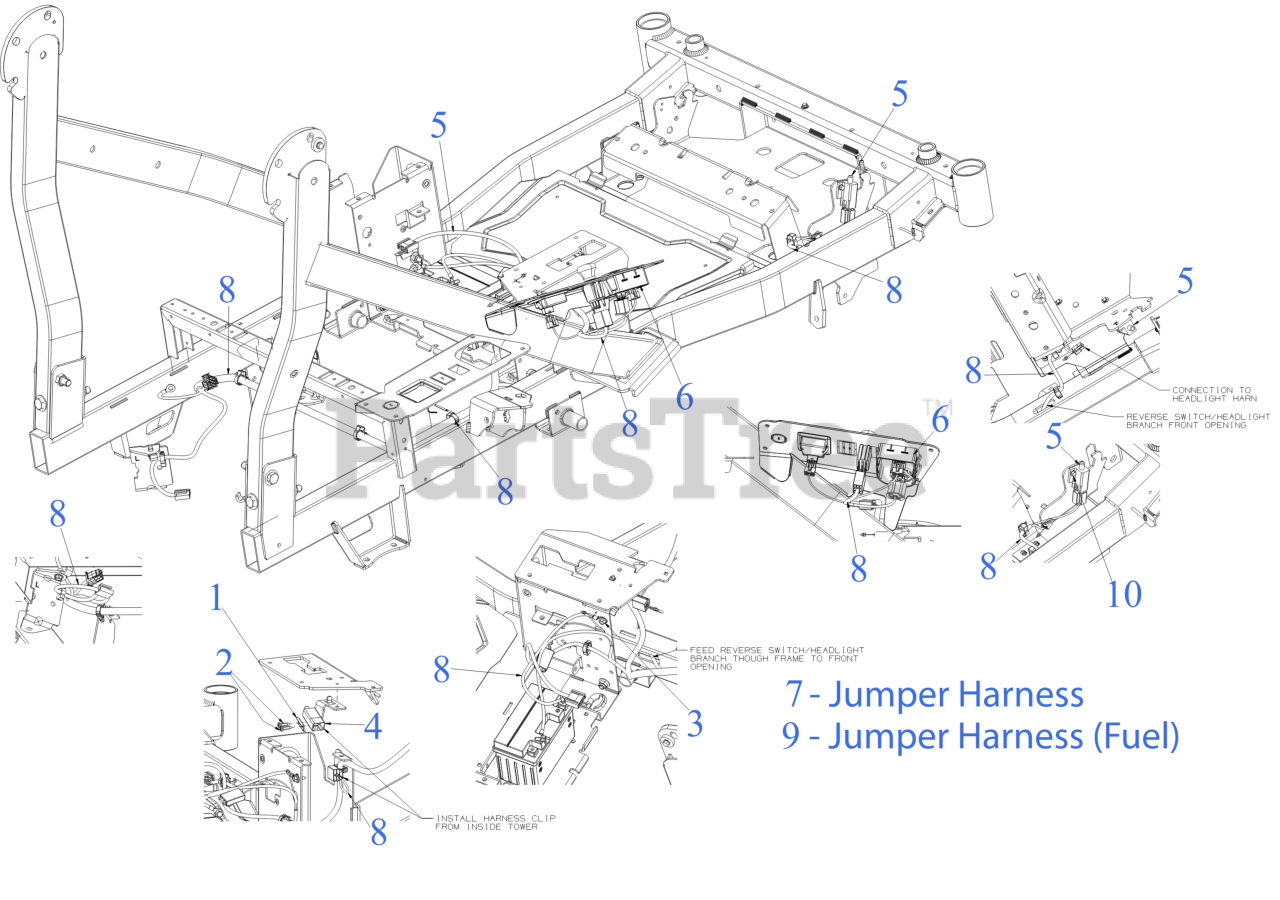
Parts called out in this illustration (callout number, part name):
1	PLATE-SWITCH
2	SCREW #10-24X11/16 T-25
3	SCREW 1/4-20X.625
4	SCREW MOUNT SWITCH NO/NC
5	INTERLOCK SWITCH (NO/NC)
6	IGNITION MODULE SWITCH (RMC ELC PTO WHTE)
7	JUMPER HARNESS (W/RELAY)
8	MAIN HARNESS (KH-ZT/KAW)
8	12V SOLENOID
9	JUMPER HARNESS (KH-ZT)
10	SHOULDER SCREW
